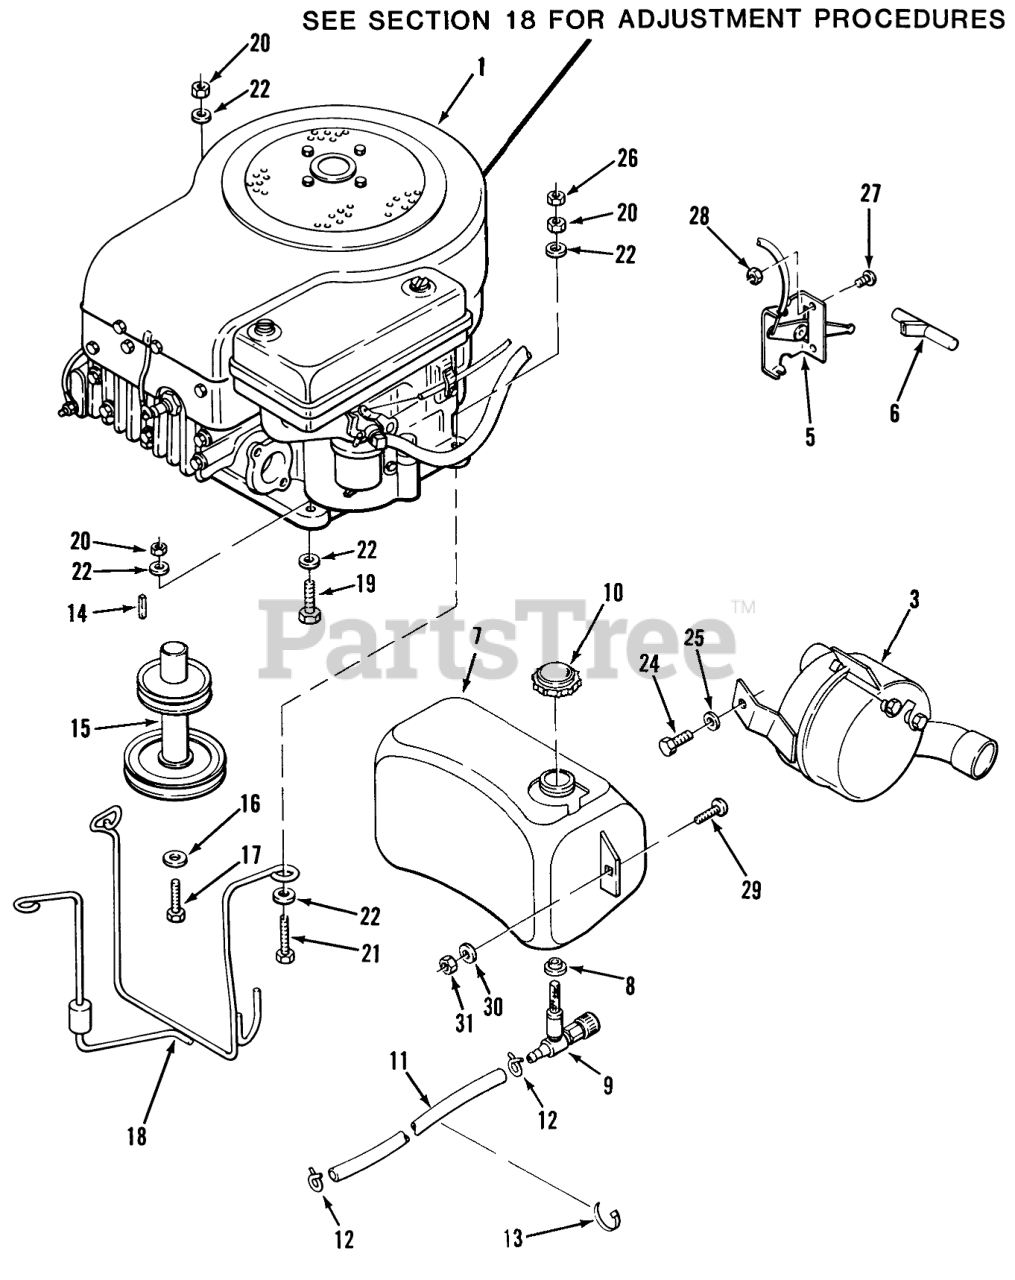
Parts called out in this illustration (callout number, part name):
1	Engine-11HP-B&S Model 252707, Type 0621-01, 211-3 Only
1	Engine-11HP-B&S Model 253707, Type 0158-03, 211-5 Only
3	Muffler-Black (includes Bolts, Heat Deflector and Spacer)
5	Choke/Throttle Control
6	KNOB-CONTROL
7	Fuel Tank
8	BUSHING
9	Valve
10	CAP GAS
11	FUEL HOSE 24" OF 6554
12	Clamp
13	PLASTIC TIE
14	Square Key
15	Pulley
16	WASHER
17	HEX HD CAP SCREW
18	ASSY BELT GUIDE B
19	HHCS
20	Nut
21	Bolt 5/16-18 x 2
22	WASHER 5/16 SAE
24	Bolt
26	Nut
27	Screw
28	Nut
29	Bolt
30	WASHER 5/16 SAE
31	Nut
